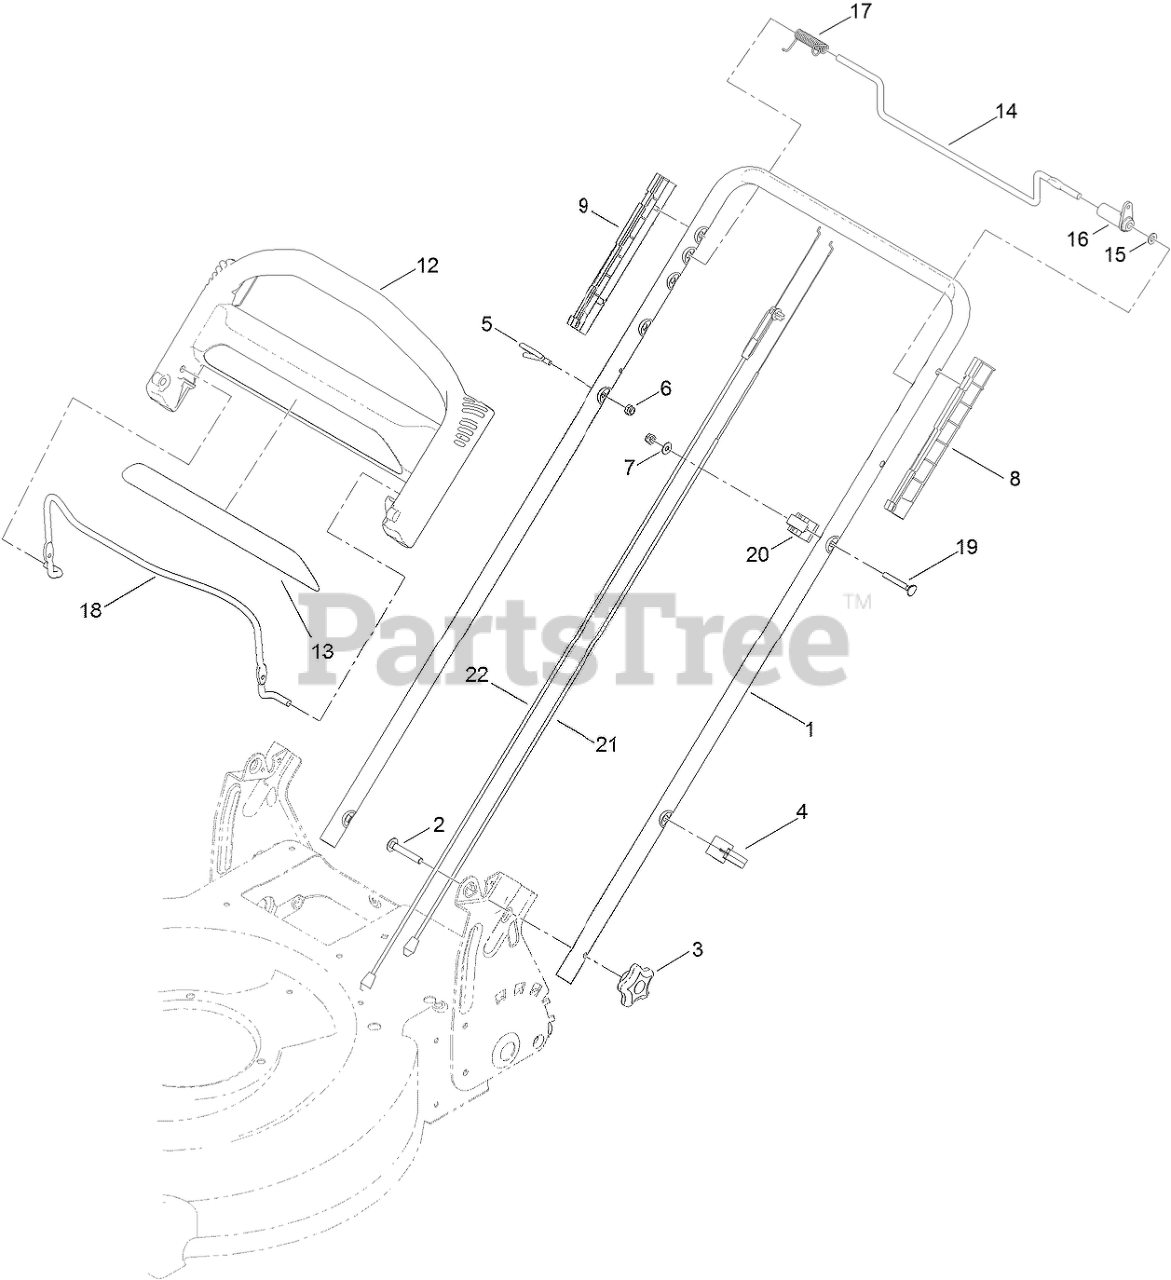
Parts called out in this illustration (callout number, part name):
2	Screw-CARR
3	KNOB-HANDLE
4	GUIDE-CABLE
5	GUIDE-ROPE
6	NUT-LOCK, NI
7	WASHER-FLAT
8	GUIDE-LH
9	GUIDE-RH
12	HANDLE-CONTROL
14	BAR-CONTROL, TRACTION
15	WASHER-PLAIN
16	LEVER-TRACTION
17	Spring-Torsion
18	Bail-Brake
19	SCREW
20	ANCHOR-CABLE
21	CABLE-TRACTION
22	CABLE-BRAKE
